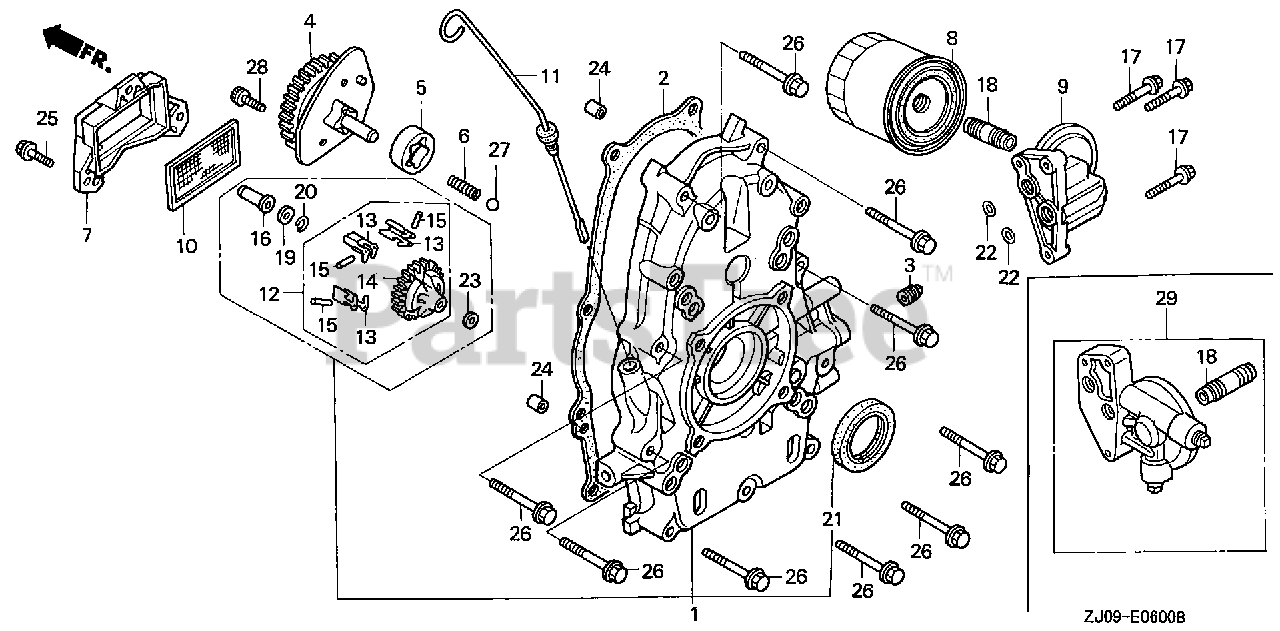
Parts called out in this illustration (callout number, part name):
1	COVER ASSY., CRANKCASE (Q-TYPE)
2	GASKET, CASE COVER
3	BOLT, SEALING
4	COVER ASSY., OIL PUMP
5	ROTOR, OIL PUMP (OUTER)
6	SPRING, RELIEF VALVE
7	COVER, OIL FILTER
8	FILTER, OIL (TOYO ROKI) (SOLD IN MULTIPLES OF 30)
8	FILTER, OIL (SOLD INDIVIDUALLY)
10	SCREEN, OIL FILTER
11	DIPSTICK, OIL
12	GOVERNOR ASSY.
13	WEIGHT, GOVERNOR
14	HOLDER, GOVERNOR WEIGHT
15	PIN, GOVERNOR WEIGHT
16	SLIDER, GOVERNOR
17	BOLT, FLANGE (6X35)
18	HOLDER, OIL FILTER
19	WASHER (6X16)
20	CLIP, GOVERNOR HOLDER
21	OIL SEAL (38X58X9)
22	O-RING (11.8X2.4)
23	WASHER, PLAIN (6MM)
24	PIN A, DOWEL (8X14)
25	BOLT, FLANGE (6X20)
26	BOLT, FLANGE (8X50)
27	BALL, STEEL (#12) (3/8)
28	BOLT, SOCKET (6X16)
29	BASE, OIL FILTER (A)
